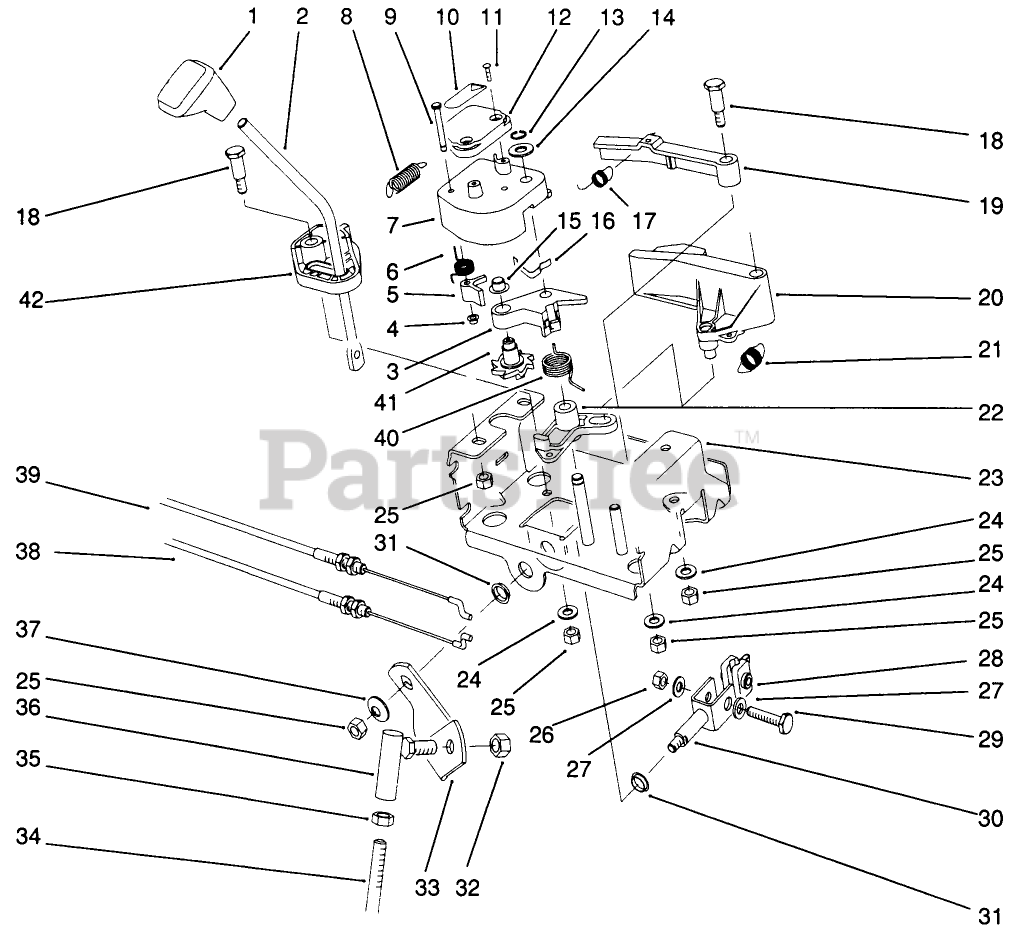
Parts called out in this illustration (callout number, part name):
1	KNOB-SHIFT
2	ROD-SHIFT
3	LEVER-WHEEL, INDEX
4	NUT-PUSH
5	TANG-INDEX
6	SPRING-TORSION
7	LEVER LATCH
8	SPRING-EXTENSION
9	PIN-TANG
10	DECAL
11	SCREW-PPH
12	COVER-LATCH
13	RING-RETAINING
14	WASHER-THRUST
15	NUT-PUSH
17	SPRING-EXTENSION
18	SCREW-SHOULDER
19	LEVER-LOCKOUT
20	LEVER-REVERSE
21	SPRING-EXTENSION
22	LEVER-REVERSE, SWITCH
24	WASHER-PLAIN
25	NUT-LOCK, NI
26	NUT-LOCK, NI
27	WASHER-FLAT
28	RETAINER-ROD, SHIFT
29	SCREW-HH
31	BUSHING
32	NUT-LOCK, NI
33	BRACKET-SHIFT
34	ROD-BENT SHIFT, LOWER
35	NUT-HJ
37	WASHER-BELLEVILLE
38	CABLE-GEARBOX
39	CABLE-ARM, LATCH
40	SPRING-TORSION
41	WHEEL-INDEX
42	BASE-LOCKOUT
